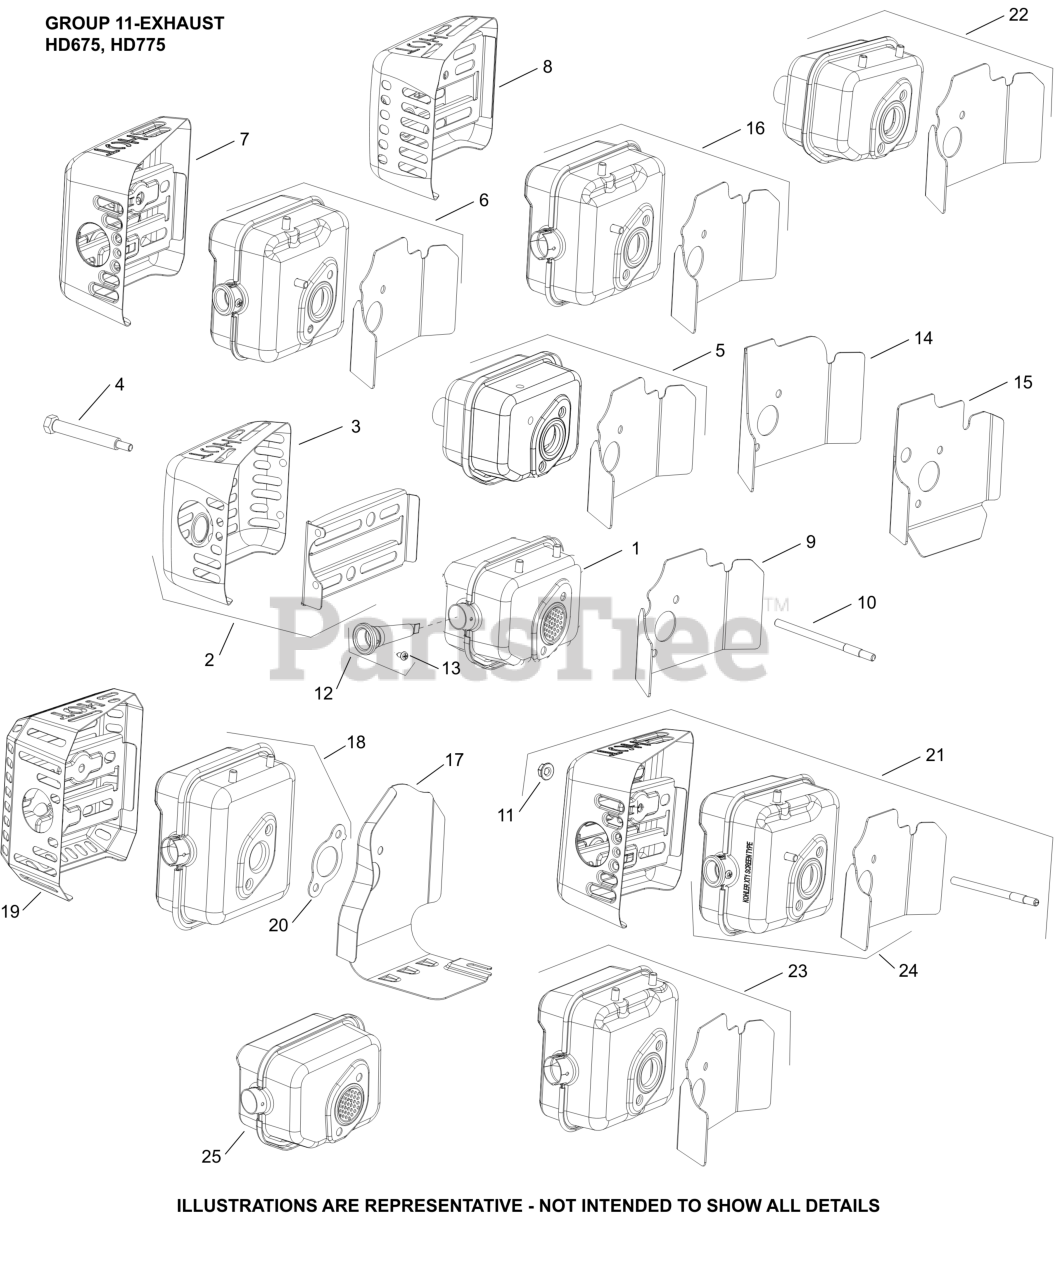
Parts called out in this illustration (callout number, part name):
7	GUARD, MUFFLER ASSEMBLY
9	GASKET, MUFFLER (HEAT DEFLECTOR)
10	STUD, EXHAUST (M6)
11	NUT, HEX FLANGE LOCK (M6)
21	KIT, MUFFLER
